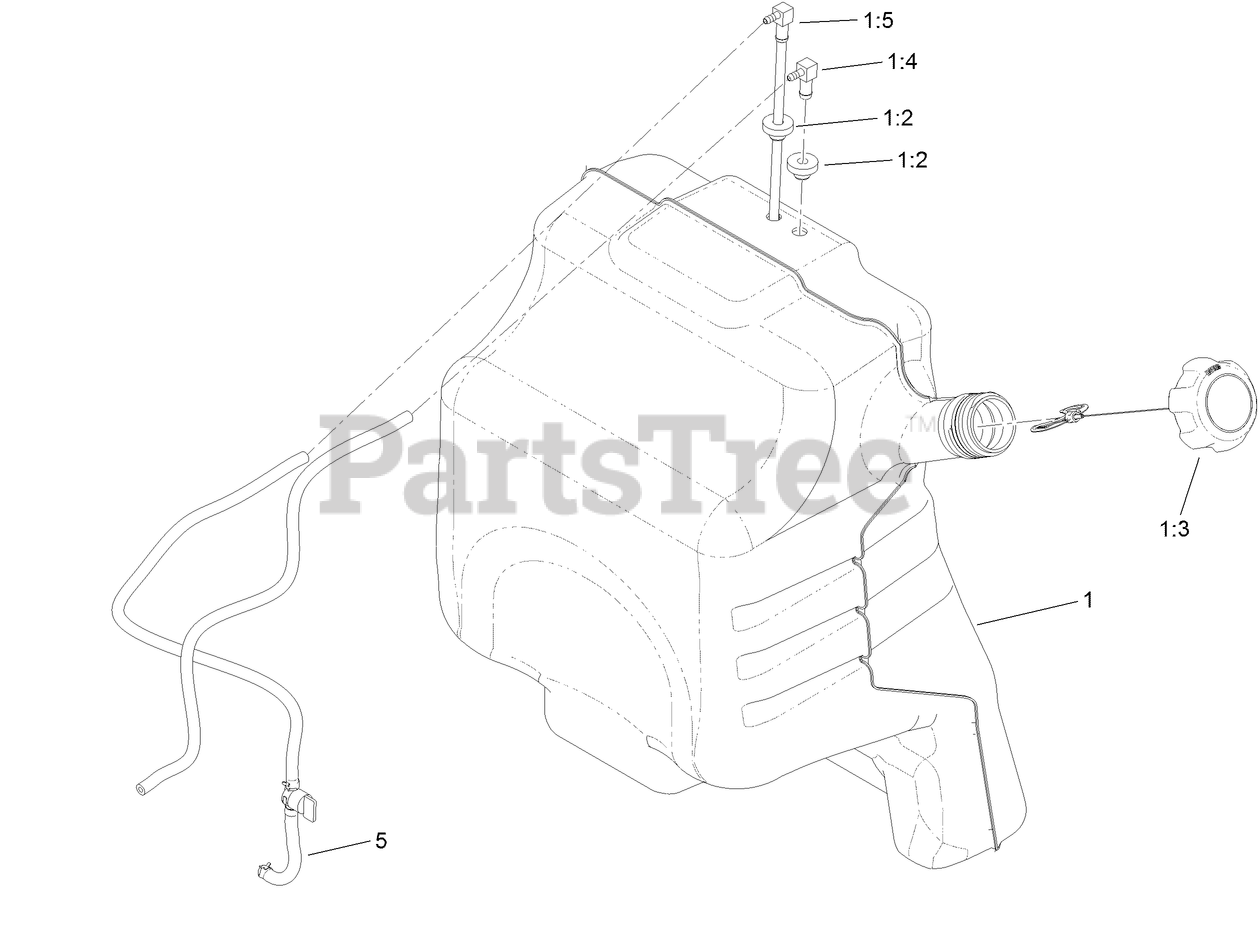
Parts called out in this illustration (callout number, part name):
1	FUEL TANK ASM
1:2	BUSHING
1:3	CAP-FUEL
1:4	FITTING-ELBOW, 90 DEG
1:5	ASM, TUBE-FUEL
5	FUEL LINE ASM
